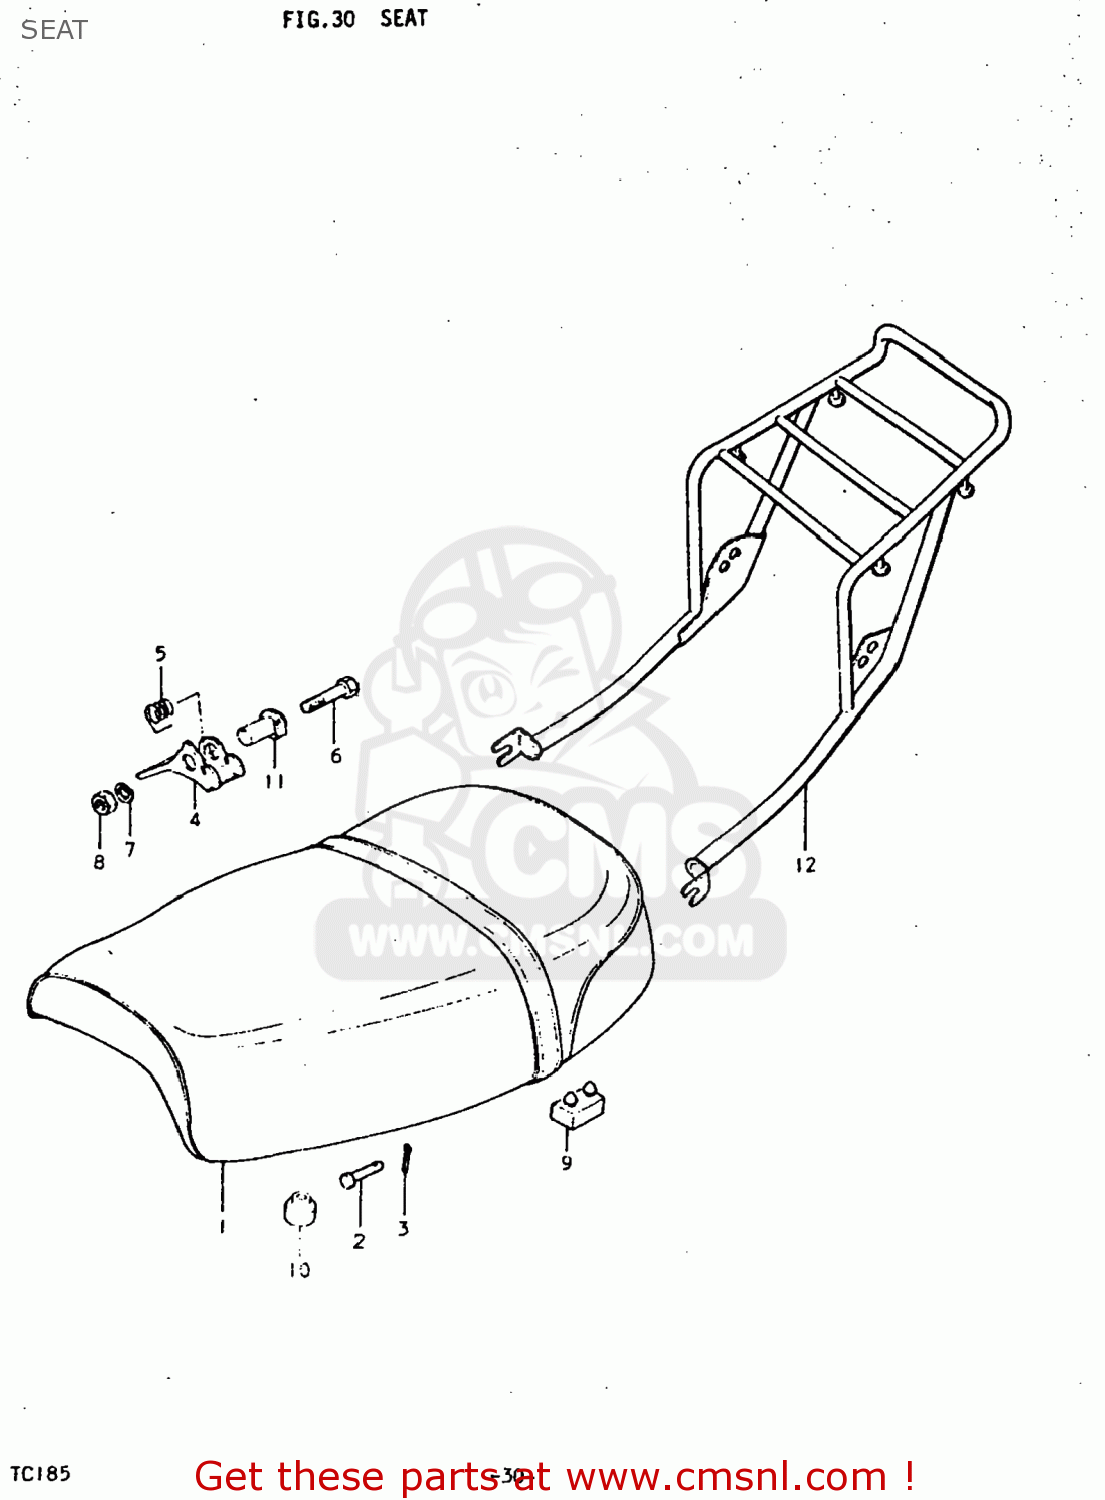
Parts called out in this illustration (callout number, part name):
1	SEAT ASSEMBLY
2	PIN
3	PIN
4	STRIKER,SEAT LOCK
5	SPRING
6	BOLT 8X45
7	LOCK WASHER
8	NUT
9	CUSHION
10	CUSHION(11.5X22X20)
11	STRIKER,SEAT LOCK
12	CARRIER
